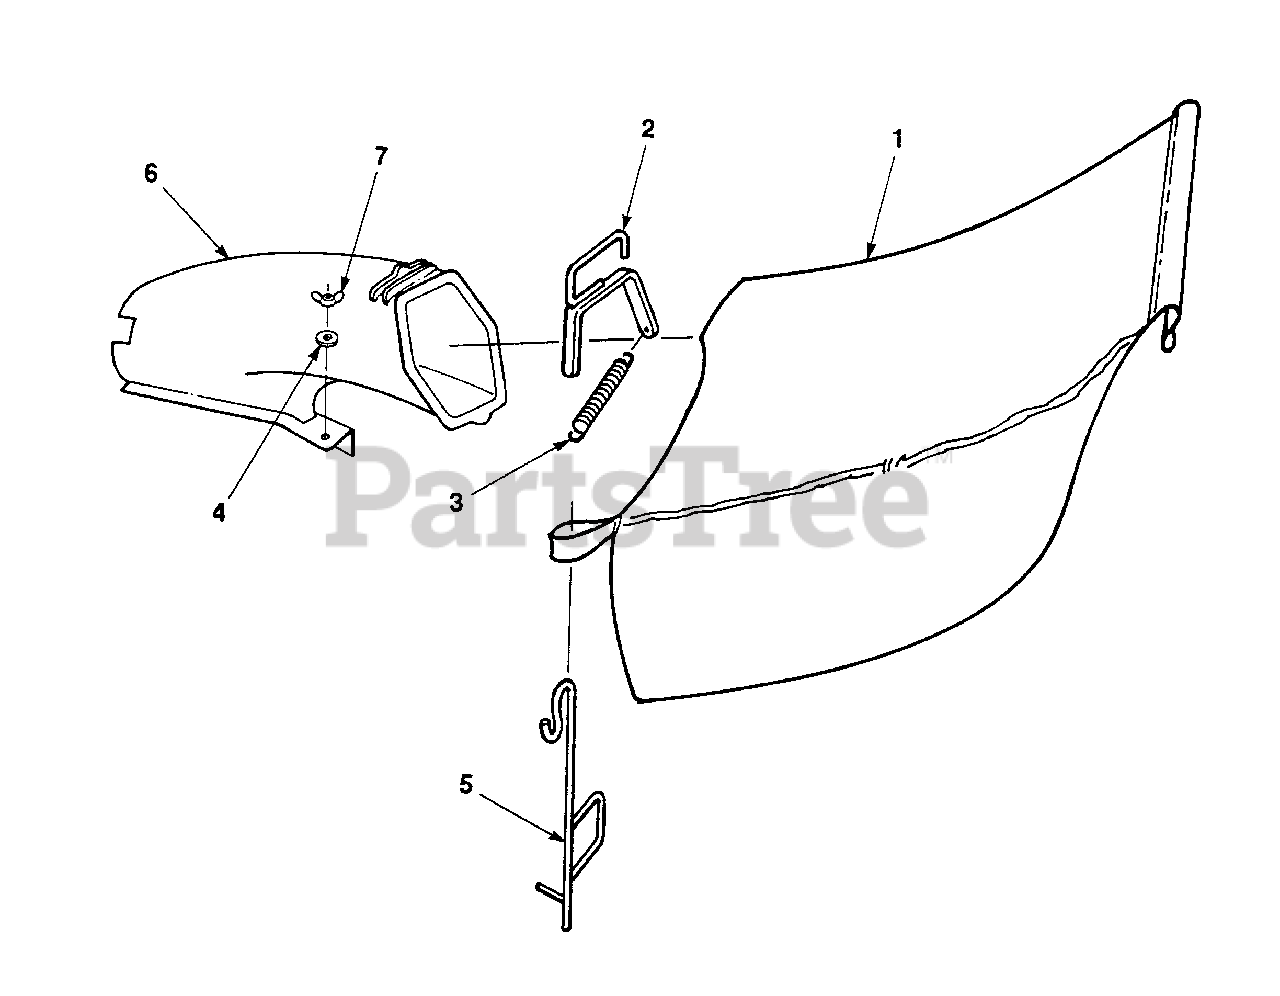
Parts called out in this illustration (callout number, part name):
1	BAG- Grass catcher
2	HANDLE & FRAME
3	SPRING- Extension
4	WASHER- Flat 1/4"
7	NUT- Wing
